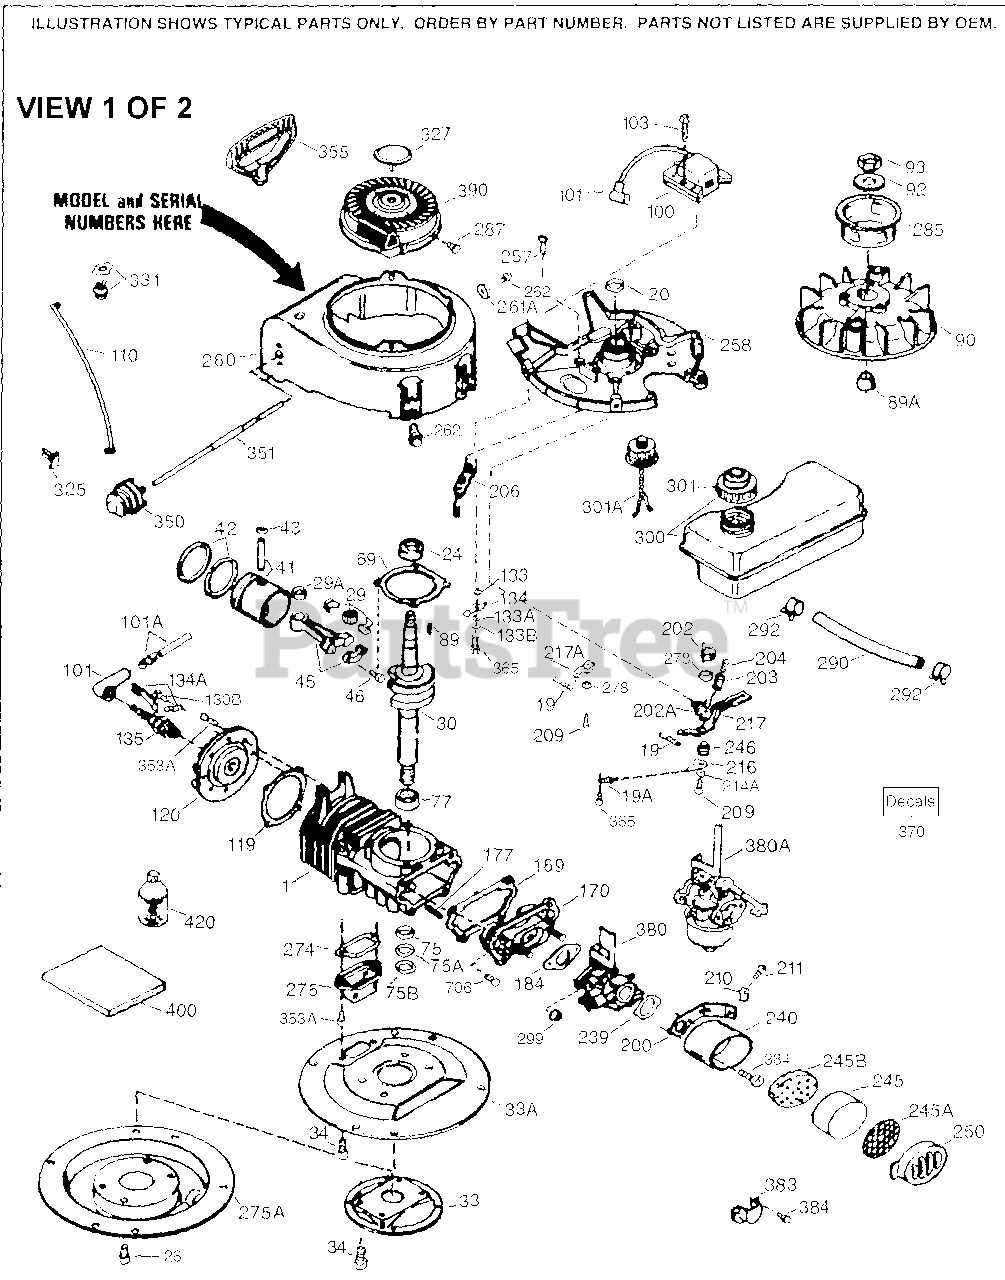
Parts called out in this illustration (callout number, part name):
1	"Cylinder
19	Extension Spring
20A	Oil Seal
20B	Oil Seal Retainer
24	Ball Bearing
28	Oil Seal
28A	Oil Seal Retainer
28B	Oil Seal Retainer Ring
29	Needle Bearing & Liner Set 37 needle s
29A	Cartridge Bearing
30	Crankshaft
38	Retainer Ring Used in early producti on
41	Piston & Pin Ass'y. (.010" OS)
41	Piston & Pin Ass'y. (Std.)
42	Ring Set (Std.)
42	Ring Set (.010" OS)
43	Piston Pin Retaining Ring
45	Connecting Rod Assy. Incl. 29, 29A & 46
46	Connecting Rod Bolt
69	* Cylinder Cover Gasket
77	Cartridge Bearing
89	Flywheel Key (also available in Packa ged Part #740007B) also available in Packaged Part #740007B
92	Belleville Washer
93	Flywheel Nut
101	Spark Plug Cover
103A	Screw, 1/4-20 x 3/4"
110	Ground Wire
119	* Cylinder Head Gasket
120	Cylinder Head
135	Resistor Spark Plug - RJ17LM
169	* Cover Plate Gasket
170	Reed & CoverPlate Ass'y. Incl. 177 & 178
177	Carburetor Mounting Stud
178	Nut & Lock Washer 1/4-28
184	* Carburetor Gasket
203	Compression Spring
204	Screw, 5-40 x 7/16"
209	Screw, Torx T-25, 10-24 x 7/8"
209	Screw, Torx T-25, 10-24 x 1/2"
211	Screw, Torx T-25, 10-32 x 5/8"
216	R.P.M. Adjusting Lever
217	Control Lever
239	Air Cleaner Gasket
240	Air Cleaner Body
245	Air Filter
245A	Air Filter
245B	Air Filter
250	Air Cleaner Cover
257	Screw, T-30, 1/4-20 x 5/8"
258	Blower Housing Base Incl. 20
262	Screw, 1/4-20 x 7/16"
274	* Exhaust Gasket (.031" thick) NOTE: S ome engines may havebeen built with t hree gaskets. In that case,two longe r mounting screws #650802 are require d.
285	Starter Cup
290	Fuel Line (8.62")
292	Fuel Line Clamp
301	Fuel Cap
331	Toggle Switch
353A	Screw, Torx T-30, 1/4-20 x 3/4"
370	Decal - Fuel/Oil Mix 24:1
370	Decal - Fuel Mix Chart 24:1
370	Name Decal
380	Carburetor (Incl. 184) (Refer to Divi sion 5, Section A, page A7-10 or Fich e 23B, Grid F-3 for breakdown)
400	* Gasket Set (Incl. items marked *)
420	2-Cycle Oil with Fuel Stabilizer - 8 oz.
